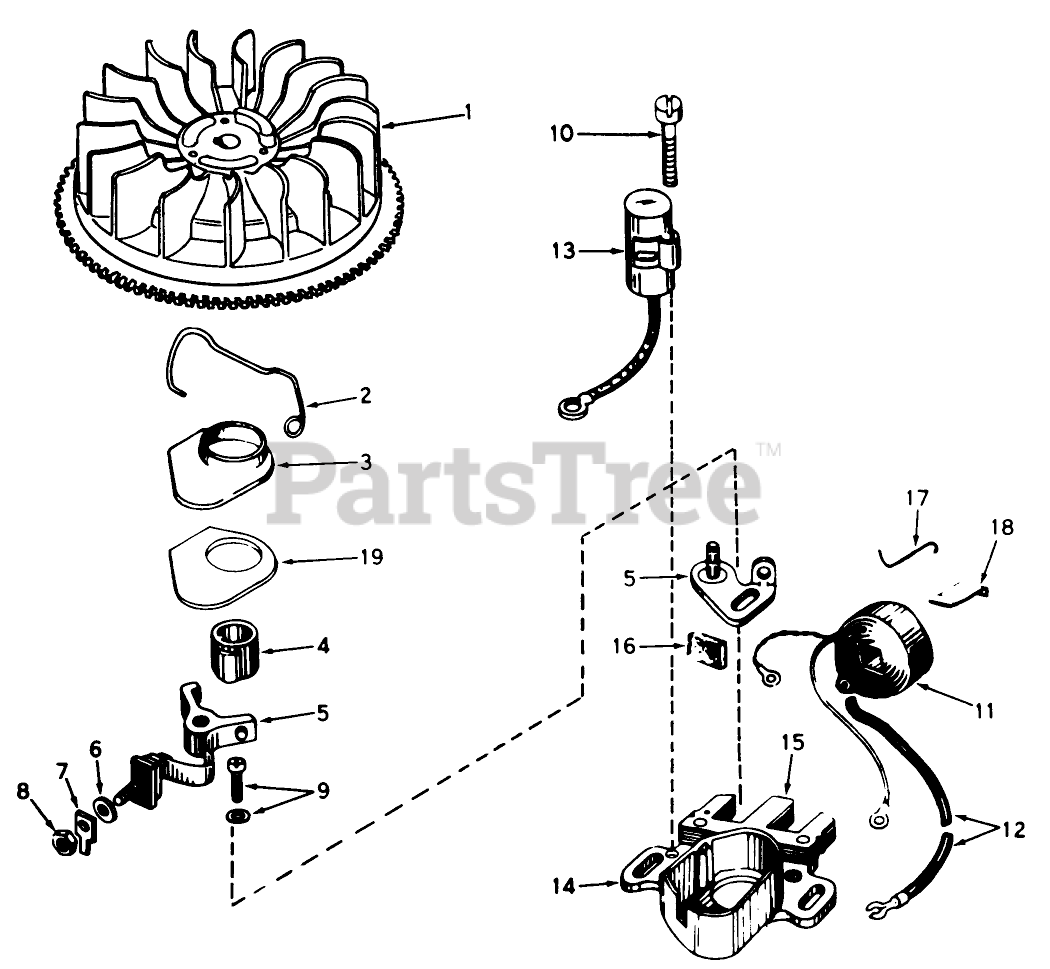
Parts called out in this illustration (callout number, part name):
1	Flywheel
2	Spring Breaker Box
3	Cover, Dust
4	Cam-Breaker
5	Breaker Assy.
6	Washer
7	Terminal
8	DECAL
9	Breaker Screw
10	Condenser Screw
11	Coil Assy. (Incl. No. 12)
12	Wire, Lead
13	Condenser
14	Core Plate
15	Stator Assy., (Incl. Nos. 2, 3, 5 thru 14 16 thru 19)
16	Felt,Cam Wiper
17	Clip, Coil
18	Spring Coil Wedge
19	Gasket Dust Cover
